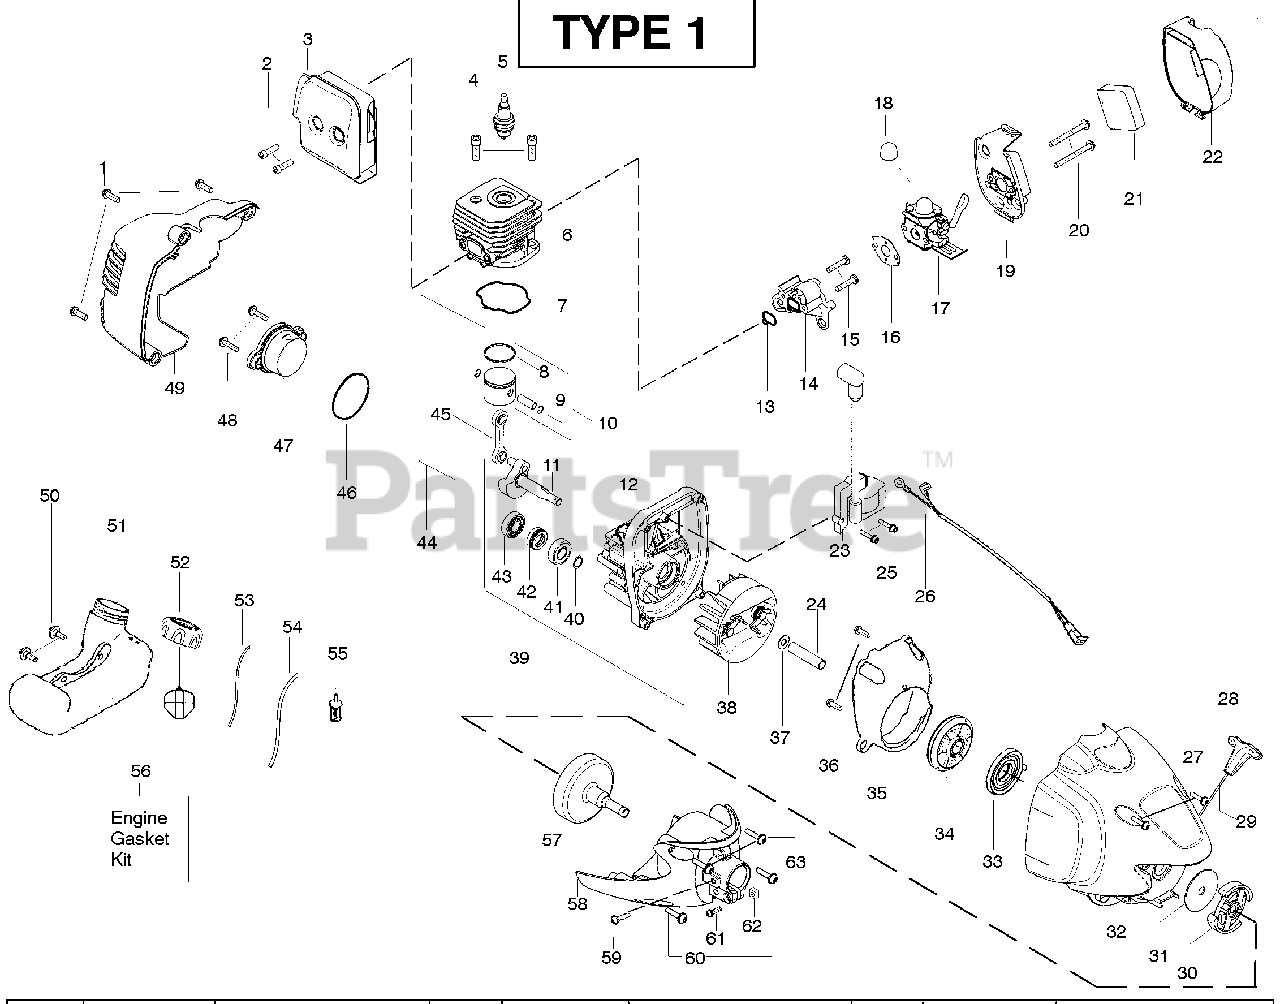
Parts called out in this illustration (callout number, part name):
3	Assy-Muffler/Shield
4	Screw-Cylinder
5	Spark Plug (RCJ 6Y)
7	Seal-Cylinder (kit)
8	Piston Ring
9	Retainer-Piston Pin
10	Kit-Piston
11	Assy-Crankshaft
12	Assy-Crankcase
13	Seal-Cyl/Carb.(kit)
14	Adapter-Carb.
16	Gasket-Carb. (kit)
17	Kit-Carb.(C1UW19)
21	Foam-Air Filter
22	Cover-Air Box
23	Ignition Module
24	Spacer-Flywheel
26	Assy-Switch wire
27	Screw
28	Handle-Starter
29	Handle-Starter
32	Washer-Clutch
33	Assy-Fan Hsg
34	Spring-Starter
35	Kit-Starter Pulley
38	Washer-Clutch Flat
39	Assy-Flywheel
40	Assy-C'case & C'shaft
41	Retain. Ring-C'shaft
42	Outer Bearing
44	Inner Bearing
45	Kit-piston/rod
46	Kit-Conn. Rod
47	O-Ring-C'case (kit)
48	Assy-Plug
51	Retainer-Tank
52	Assy-Fuel Tank
53	Assy-Fuel Cap
54	Kit-Fuel Line (Small)
55	Kit-Fuel Line (Large)
56	Assy-Fuel Pickup
57	Kit-Engine Gasket
58	Assy-Clutch Drum
59	Assy-Clutch Cover
